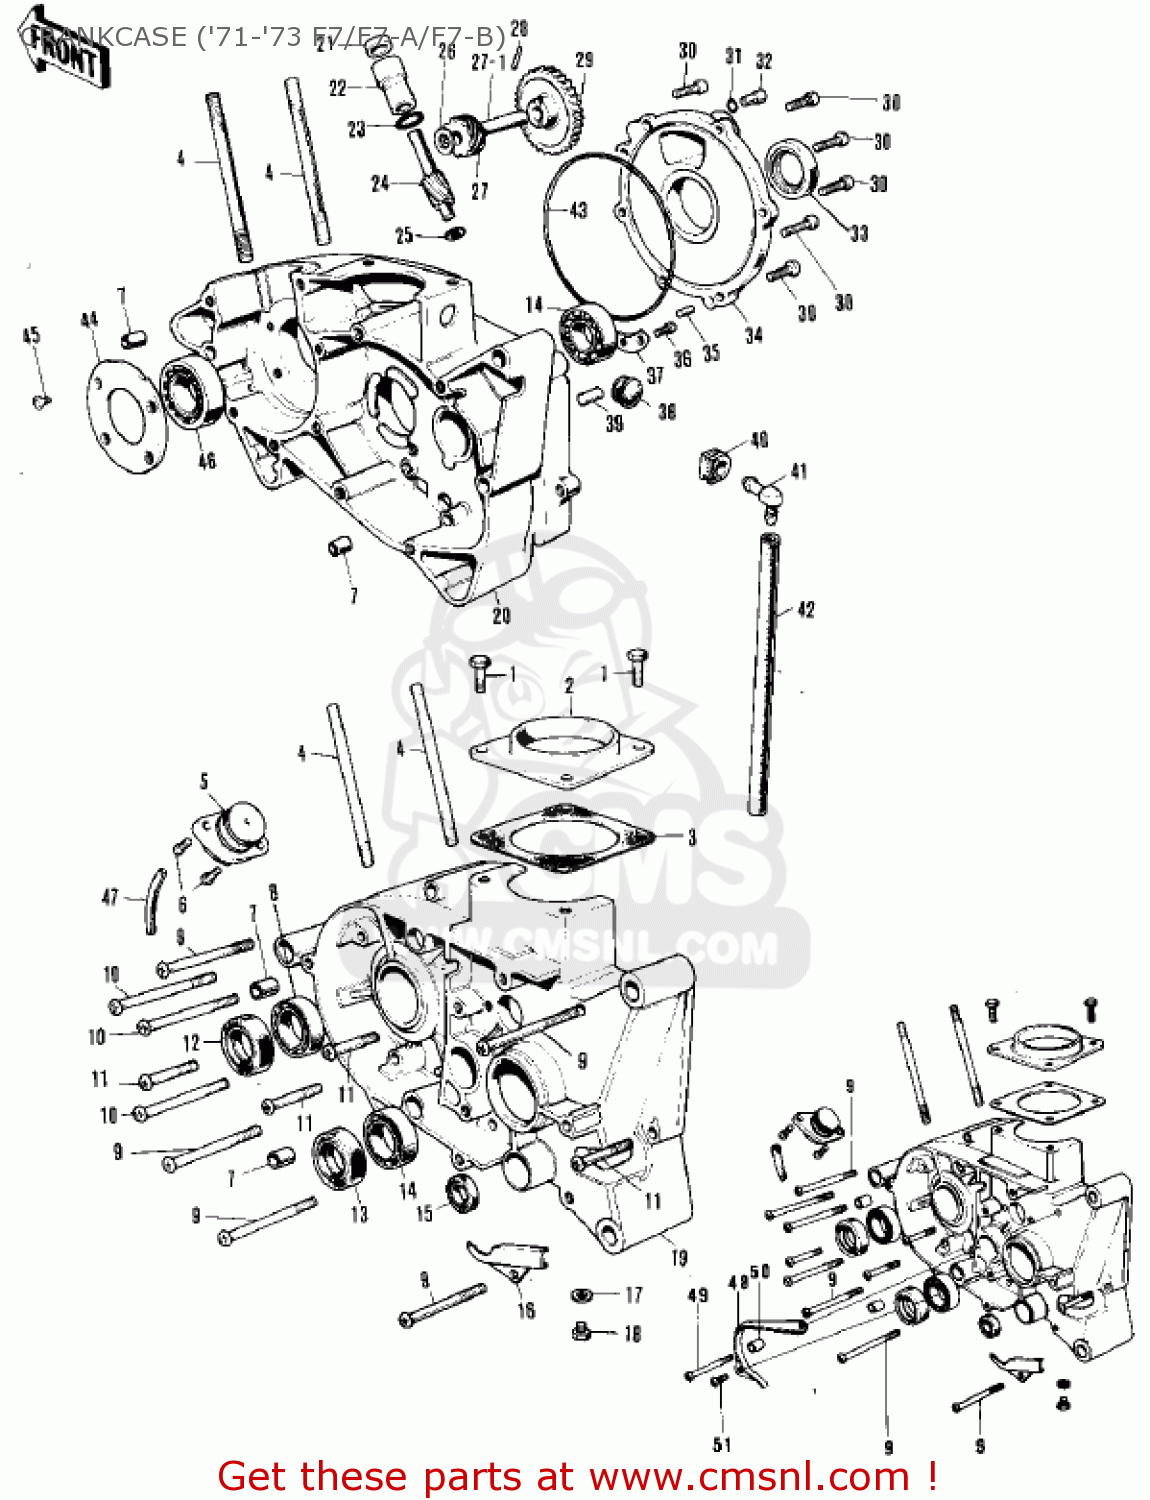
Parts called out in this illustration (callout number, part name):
1	BOLT 6X20
2	INLET PIPE
3	GASKET-INLET PIPE (NAS)
4	STUD,8X70
5	PUMP,FUEL DRIN
6	SCREW-PAN HEAD,6X16
7	PIN,DOWEL,10X8.2X14
8	BEARING-BALL,#6205C3
9	SCREW-PAN HEAD,6X65
10	SCREW-PAN HEAD,6X55
11	SCREW-PAN HEAD,6X40
12	SEAL-OIL
13	OIL SEAL SC30426
14	BEARING-BALL,6204C3
15	OIL SEAL SB12205
16	COVER-WIRING HARNESS
17	GASKET, 10,5X16X1 (NAS)
18	PLUG-OIL DRAIN
19	CRANKCASE,L.H
20	CRANKCASE,RH
21	OIL SEAL
22	BUSH-TACHOMETER
23	'O' RING
24	GEAR-TACHOMETER
25	WASHER-THRUST
26	WASHER-THRUST
27	GEAR-TACHOMETER
28	PIN,DOWEL,2.5X12.8
29	GEAR-OIL PUMP
30	SCREW-PAN HEAD,6X20
31	RING-O,CHECK VALVE
32	VALVE-CHECK
33	OIL SEAL,TB32457
34	COVER-ROTARY DISC VLV
35	ROLLER,5X12
36	SCREW-PAN HEAD,6X12
37	HOLDER-MISSION BERNG
38	GROMMET,PIPE
39	PIN-DOWEL,8X16
40	GROMMET
41	BREATHER
42	PIPE-BREATHER
43	RING-O,120MM
44	HOLDER-CRANK BEARING
45	SCREW-CNTSNK HD,6X16
46	BEARING-BALL,#6305C3
47	PIPE-FUEL OVERFLOW
48	GUIDE-CHAIN
49	SCREW-PAN HEAD,6X85
50	COLLAR,6.8X10X16
51	SCREW-PAN HEAD,6X12
